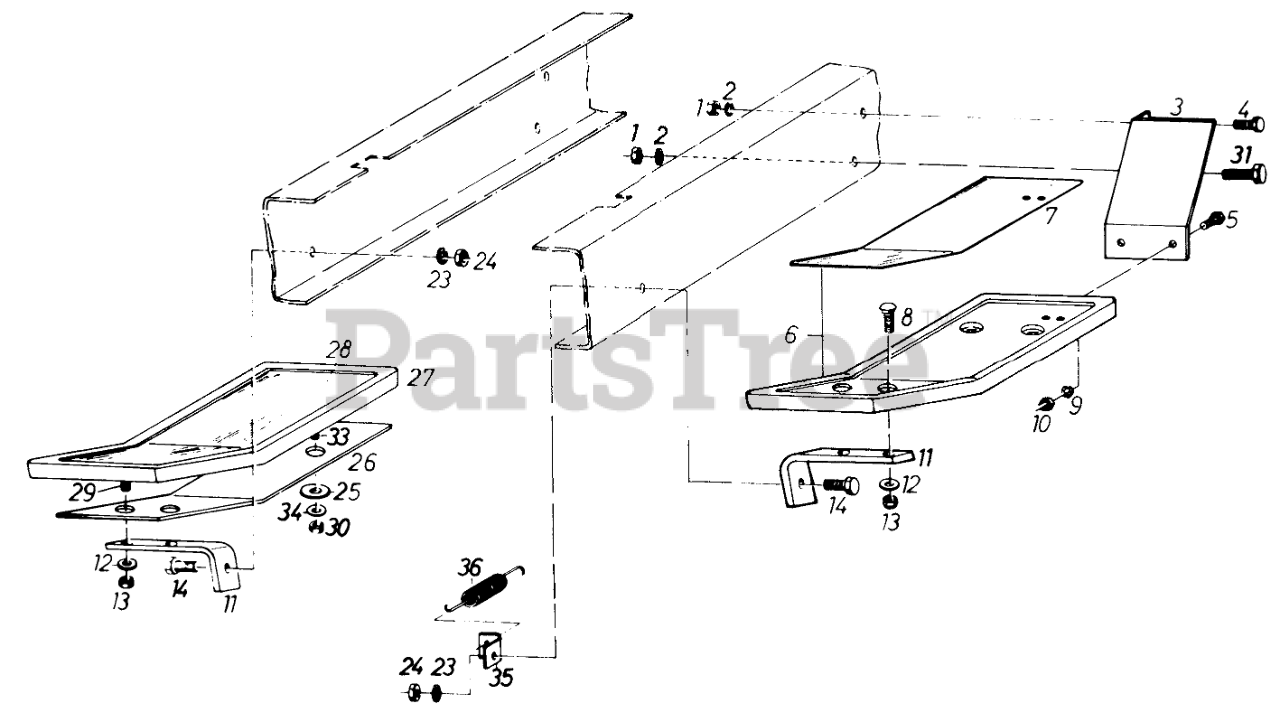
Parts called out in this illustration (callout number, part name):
2	Lockwasher
3	Foot Board Support Left
3	Foot Board Support Right
5	Screw
6	Foot Board Left Assy. (Only Deliverable Part 7 and 8)
7	Rubber Plate
8	Screw
9	Washer
11	Foot Board Support
12	Washer
23	Washer
25	Washer
27	Foot Board Right Assy. (Only Deliverable Part 25, 26, 28, 29, 30, 33 and 34)
28	Rubber Plate
29	Screw
33	Screw
34	Washer
35	Holder
36	Spring
